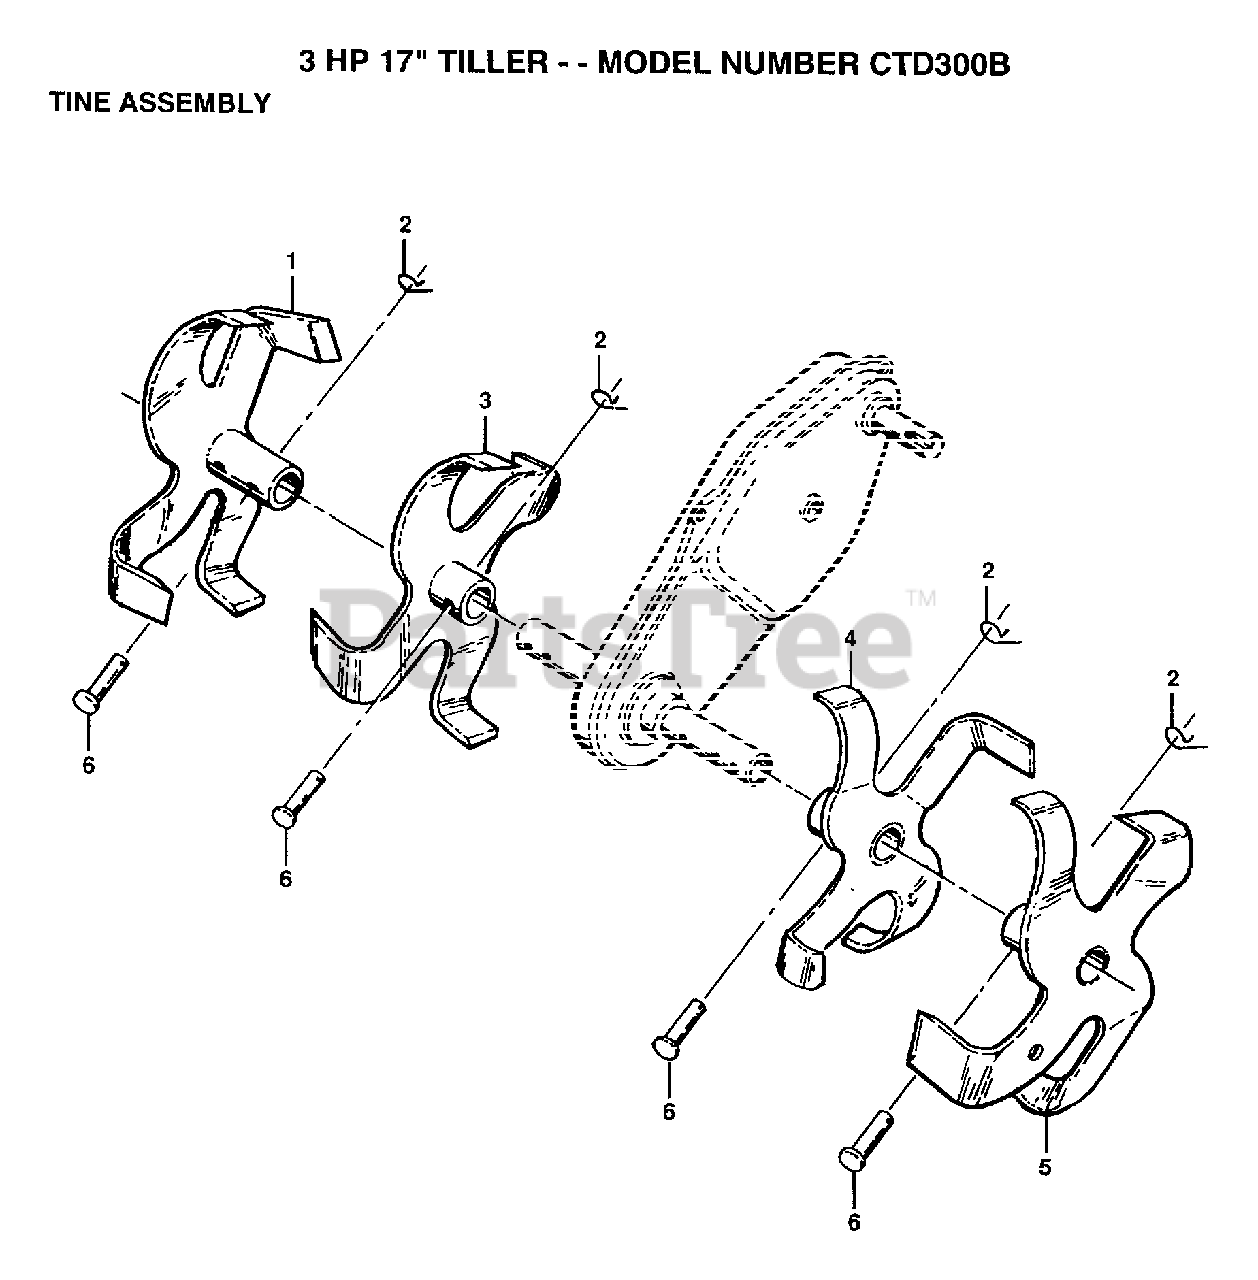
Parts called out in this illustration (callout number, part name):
1	TINE ASSY RH
2	SPRING.RETAINER
3	TINE ASSY RH
4	TINE INN LH TI
5	TINE ASS'Y LH
6	DRILLED RIVET RT
